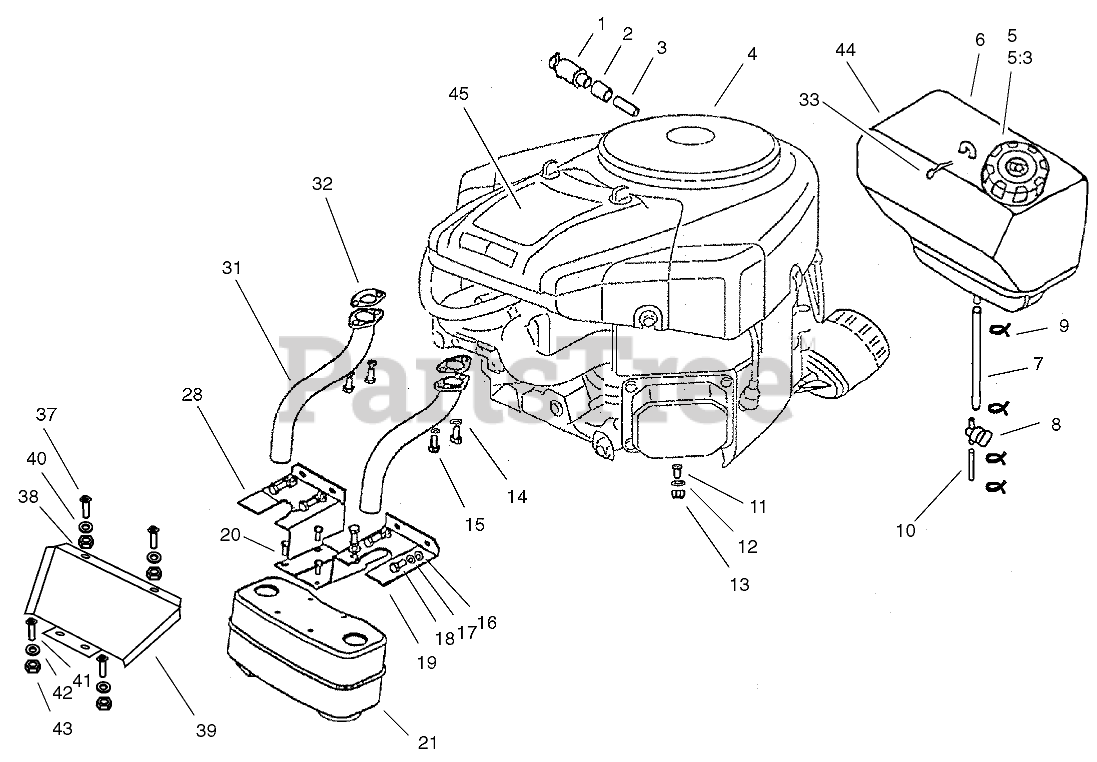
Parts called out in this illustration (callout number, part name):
1	VALVE-OIL DRAIN
2	COUPLER-OIL DRAIN
3	FITTING-OIL DRAIN
5	GAS CAP ASM
5:3	GASKET-CAP, GAS
6	TANK-FUEL
7	LINE-FUEL
8	VALVE-TANK, FUEL
9	CLAMP-LINE, FUEL
10	LINE-FUEL
11	BOLT-HHF
12	WASHER-PLAIN
13	NUT-LOCK, NI
14	WASHER-SPRING
15	SCREW-HH
16	WASHER-PLAIN
17	WASHER-SPRING
18	SCREW-HH
19	GUARD-MUFFLER, LH
20	SCREW-HWH
21	MUFFLER
28	GUARD-MUFFLER, RH
30	TUBE-EXHAUST, LH
31	TUBE-EXHAUST, RH
32	GASKET-EXHAUST
33	PIN-HAIR
37	SCREW-HH
38	NUT-LOCK
39	SHIELD-HEAT
40	WASHER-FLAT
42	WASHER-FLAT
43	NUT-LOCK
44	TANK-FUEL W/CAP
45	DECAL-ENGINE
